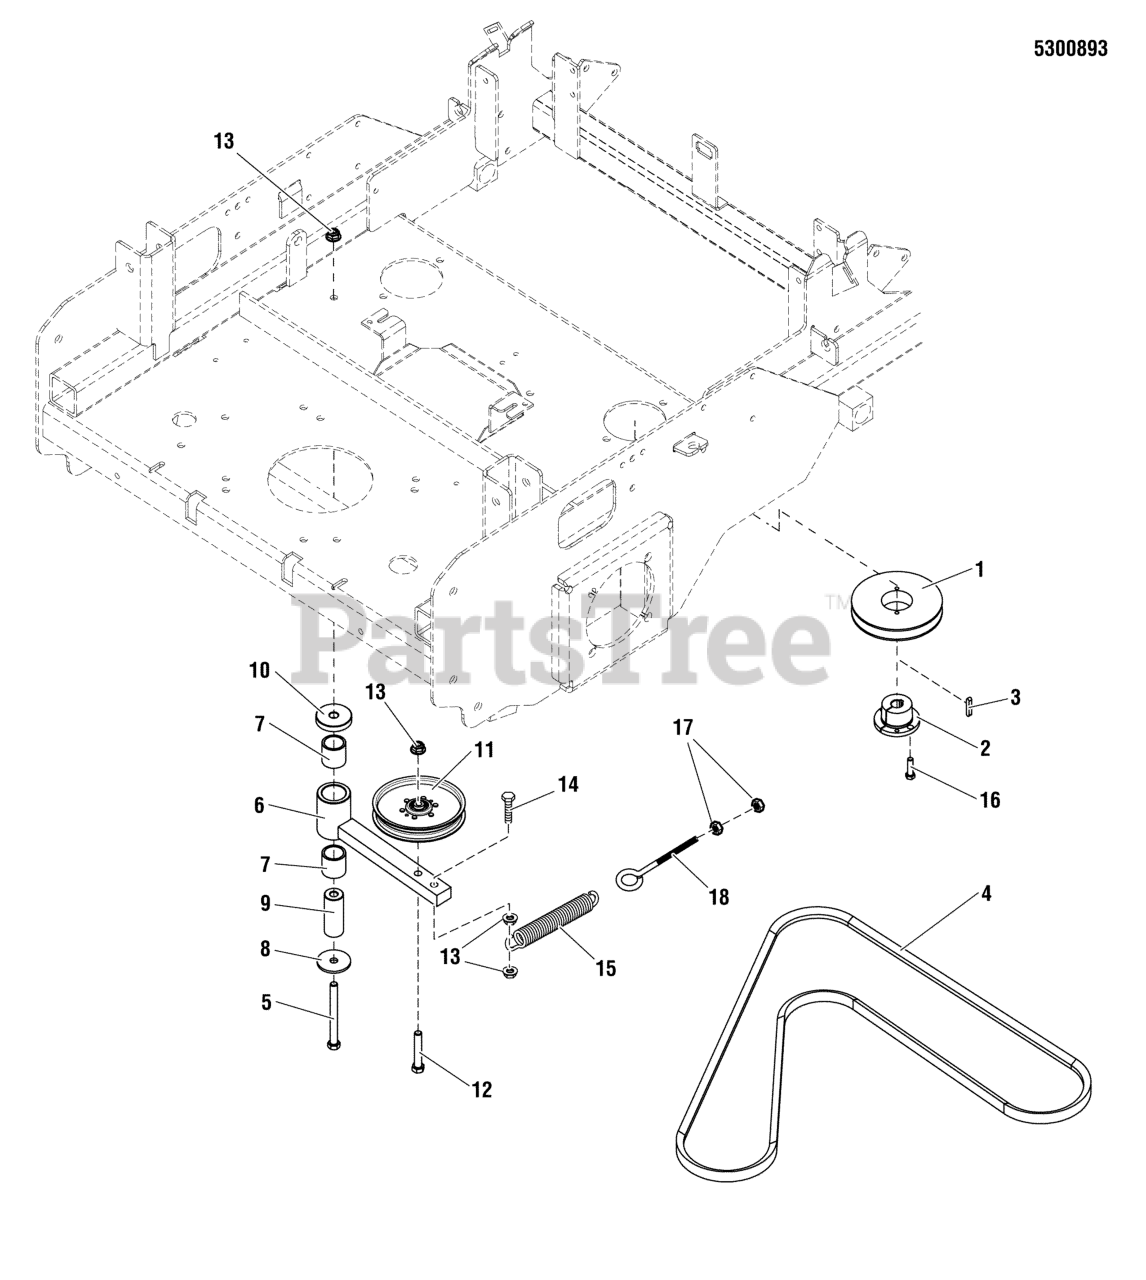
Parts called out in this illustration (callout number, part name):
1	PULLEY, SPLIT STEEL 5.632 OVER BALL
2	BUSHING, TAPERED HUB
3	KEY, 5MM SQ. W/ RADIUS
4	BELT, #7-9502, B-SECT - EL 67.8, HYDRO
5	BOLT, 3/8-16 X 4" GD5 CZ
6	WELD, ARM, PUMP DRIVE IDLER - BLK
7	BUSHING, BRASS, 1.25X1X1.25
8	WASHER, .41 X 1.75 X .14
9	SPACER, .39 X 1.00 X 2.55, SS
10	SPACER, .45 X 1.88 X .38
11	PULLEY, IDLER
12	BOLT, 3/8-16 X 2-1/4" GD5 CZ
13	NUT, 3/8-16 HEX NYLOCK FLANGE
14	BOLT, 3/8-16 X 1-3/4" GD5 CZ
15	SPRING, EXTENSION, SWIVEL END
16	BOLT, 1/4-20 X 1" GD5 CZ
17	NUT, 3/8-16 HEX
18	EYE BOLT, 3/8-16 X 5, 2.88THRD, 1EYE, CZ
